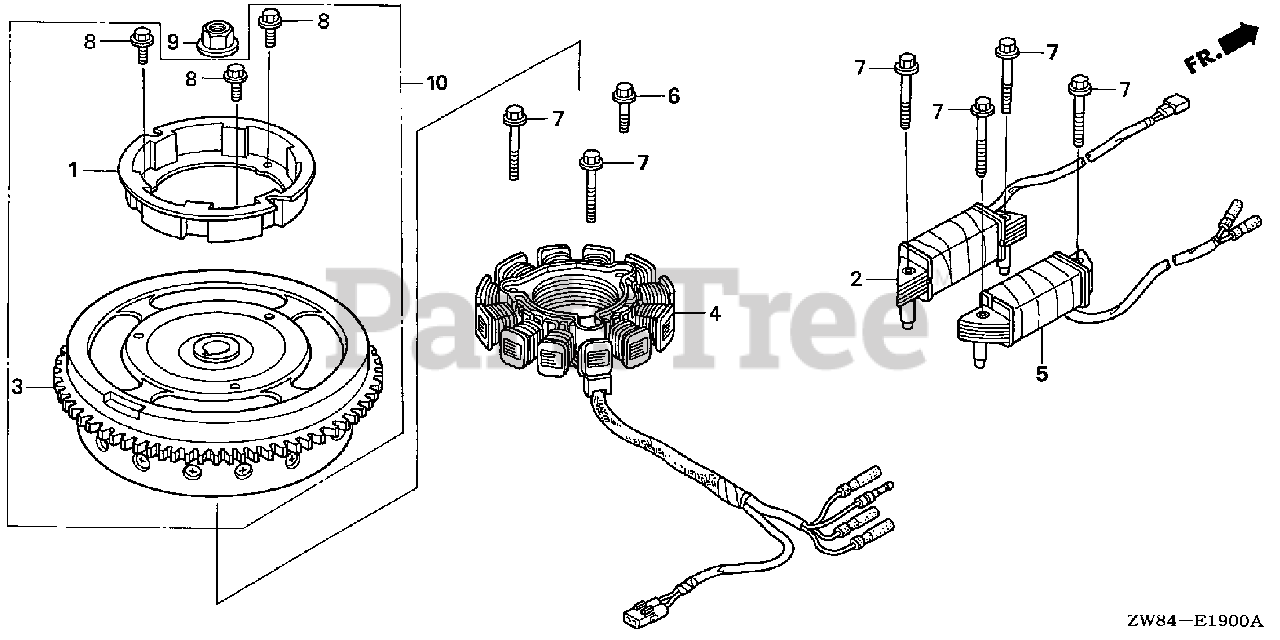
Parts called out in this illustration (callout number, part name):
1	PULLEY, STARTER
3	FLYWHEEL *TBLACK* (BLACK)
4	COIL ASSY., CHARGE (12A)
6	BOLT, FLANGE (6X36) (CT200)
7	BOLT, FLANGE (6X52) (CT200)
8	BOLT, FLANGE (6X10)
9	NUT, SPECIAL (14MM)
10	FLYWHEEL *TBLACK* (SELF STARTER) (BLACK)
